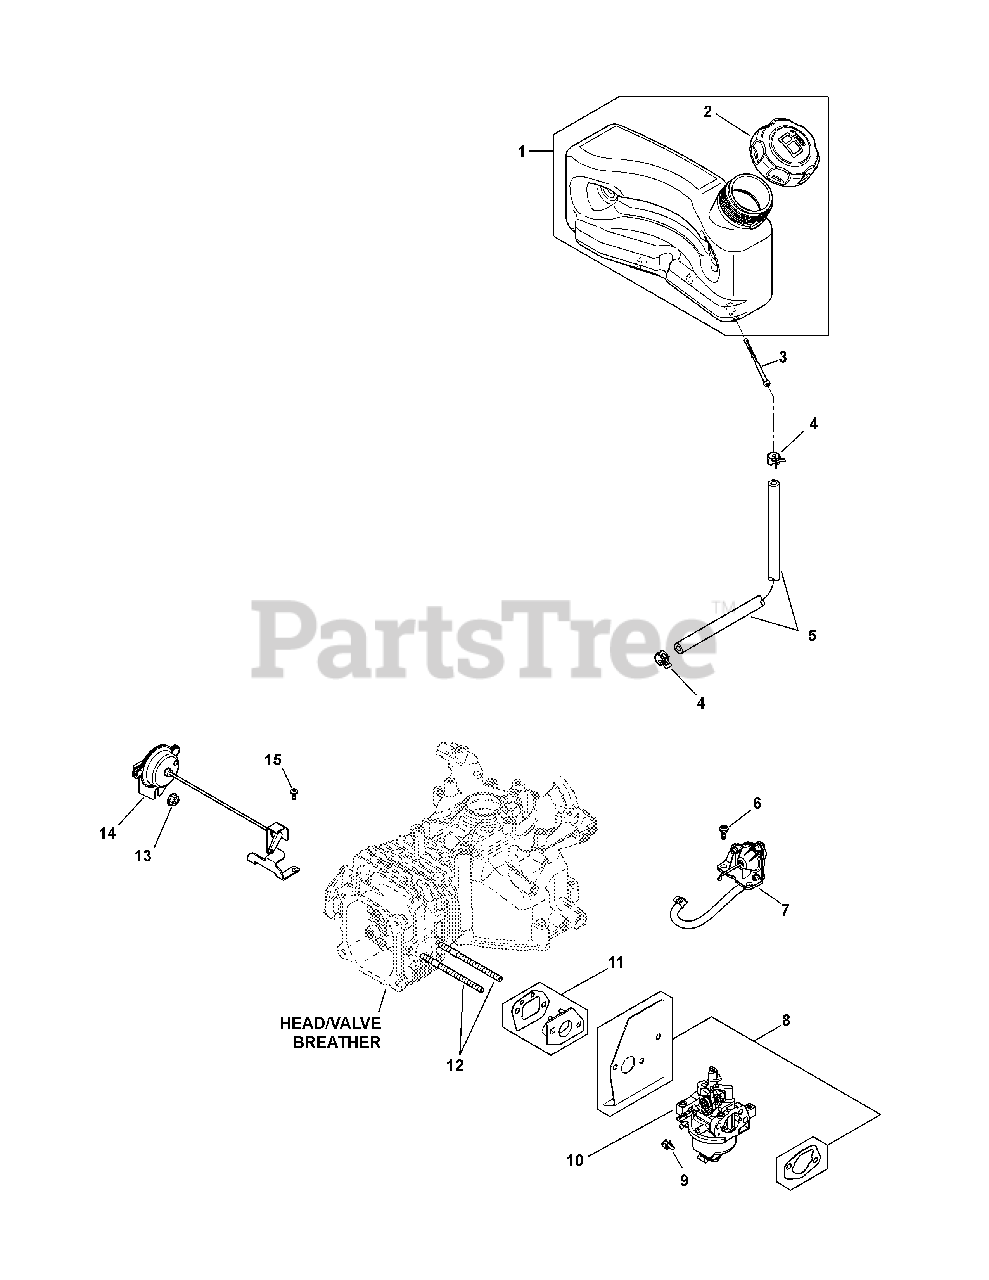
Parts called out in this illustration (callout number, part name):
1	Kit, Fuel Tank (Includes 2)
2	Cap, Fuel Assy.
3	Filter, Fuel In-Nipple
5	Line, Fuel (24"-Cut To Length)
6	Screw, Shoulder
7	Diaphragm, Assembly
8	Kit, Carb Gasket
10	Kit, Carburetor W/Gaskets (Includes 8)
11	SPACER, CARBURETOR
12	Stud, M6X1.0X93
13	Nut, Flg M6X1.0
14	Arm, Assembly
15	Screw, M4 Thread Forming
